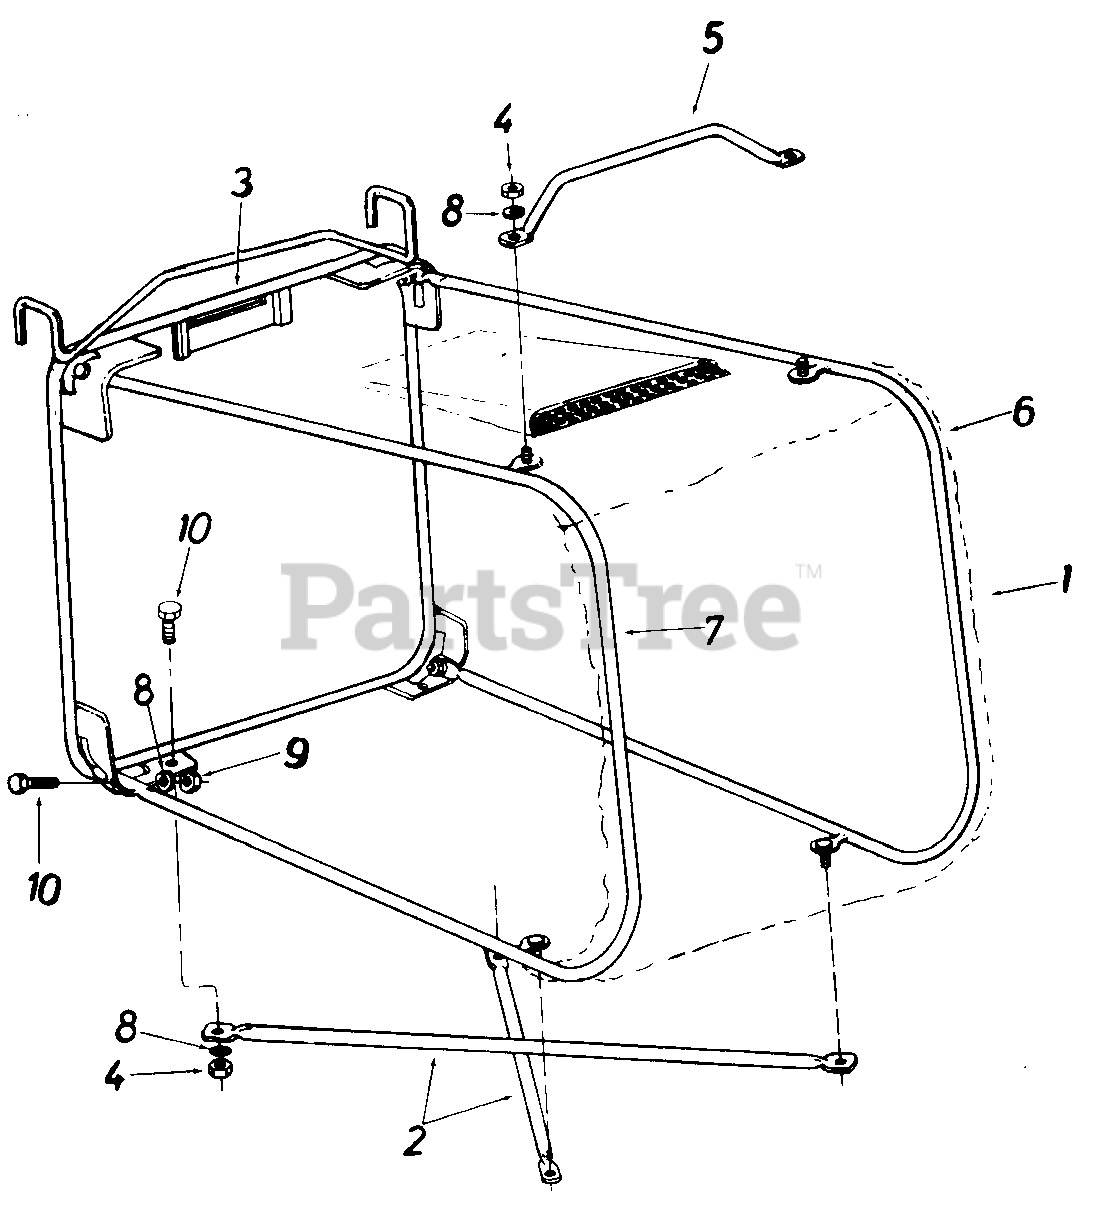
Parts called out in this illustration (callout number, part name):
1	G rass Catcher Bag
2	Bottom Cross Brace
3	Grass Catcher Frame Ass'y.
4	Hex Cent. L-Nut 1/4-2 Thd.
5	Grass Catcher Handle
9	Hex Cent. L.-Nut 1/4-20 Thd.
10	Hex Bolt 1/4-20 x .62" Lg.*
